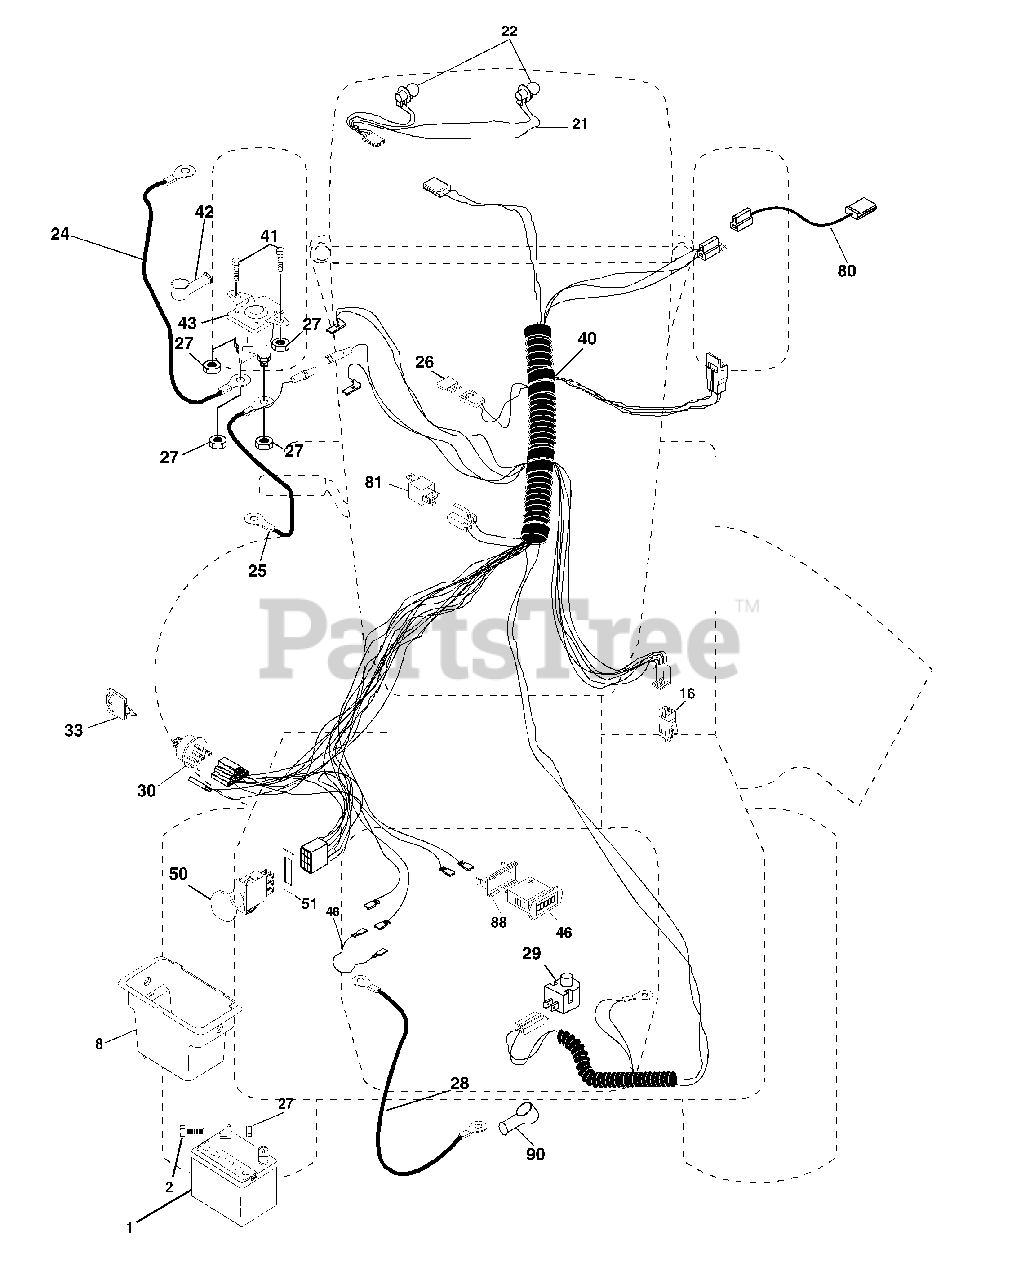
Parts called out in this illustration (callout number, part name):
1	Battery 12 Volt 28 AMP
2	Bolt Hex Hd 1/4-20unc X 3/4
8	Battery Box
16	Switch Interlock Push-In
21	Harness Asm Light W/4152j
22	Bulb Light #1156
24	Cable Battery 6 Ga 11" red
25	Cable Battery 6 Ga 44" red w/16 wire
27	Nut Keps Hex 1/4-20 Unc
28	Cable Ground 6 Ga 12" black
29	Switch Plunger Nc Gray
30	Switch Ign
33	Key Ign Generic
40	Harness Ign.
41	Bolt Blk Fin Hex 1/4 - 20 x 1/2
42	Cover Terminal Red
43	Solenoid
46	Meter Hour
48	Adapter Ammeter
50	Switch PTO
51	Ring Retainer PTO
80	Harness Clutch Evx
81	Relay Asm.
89	Bracket Snap-In Hourmeter
90	Cover Terminal
